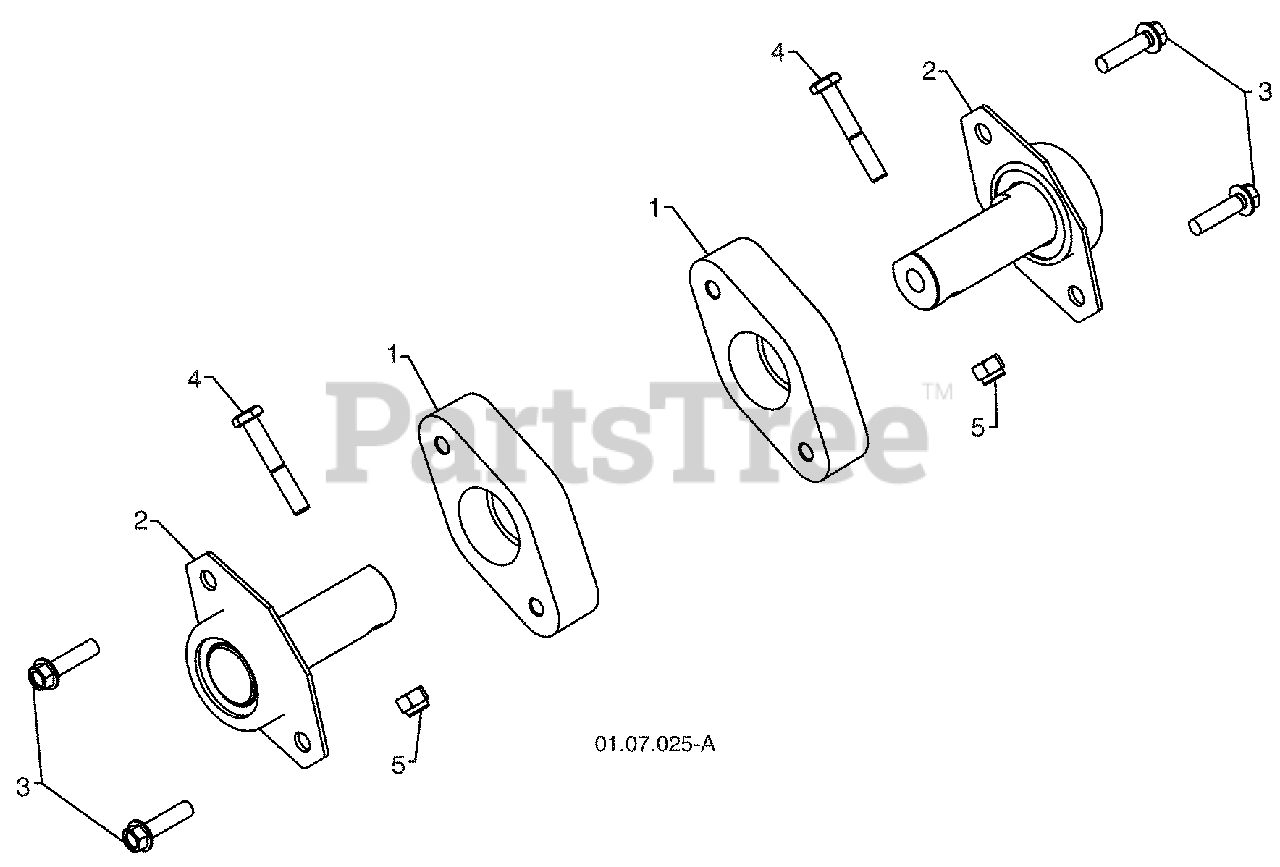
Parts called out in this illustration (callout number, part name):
1	PLASTIC RETAINER
2	AUGER BALL BEARING
3	SCREW 5/16-18 x 1.00
4	SCREW 1/4-20 x .625
5	NUT 1/4-20
